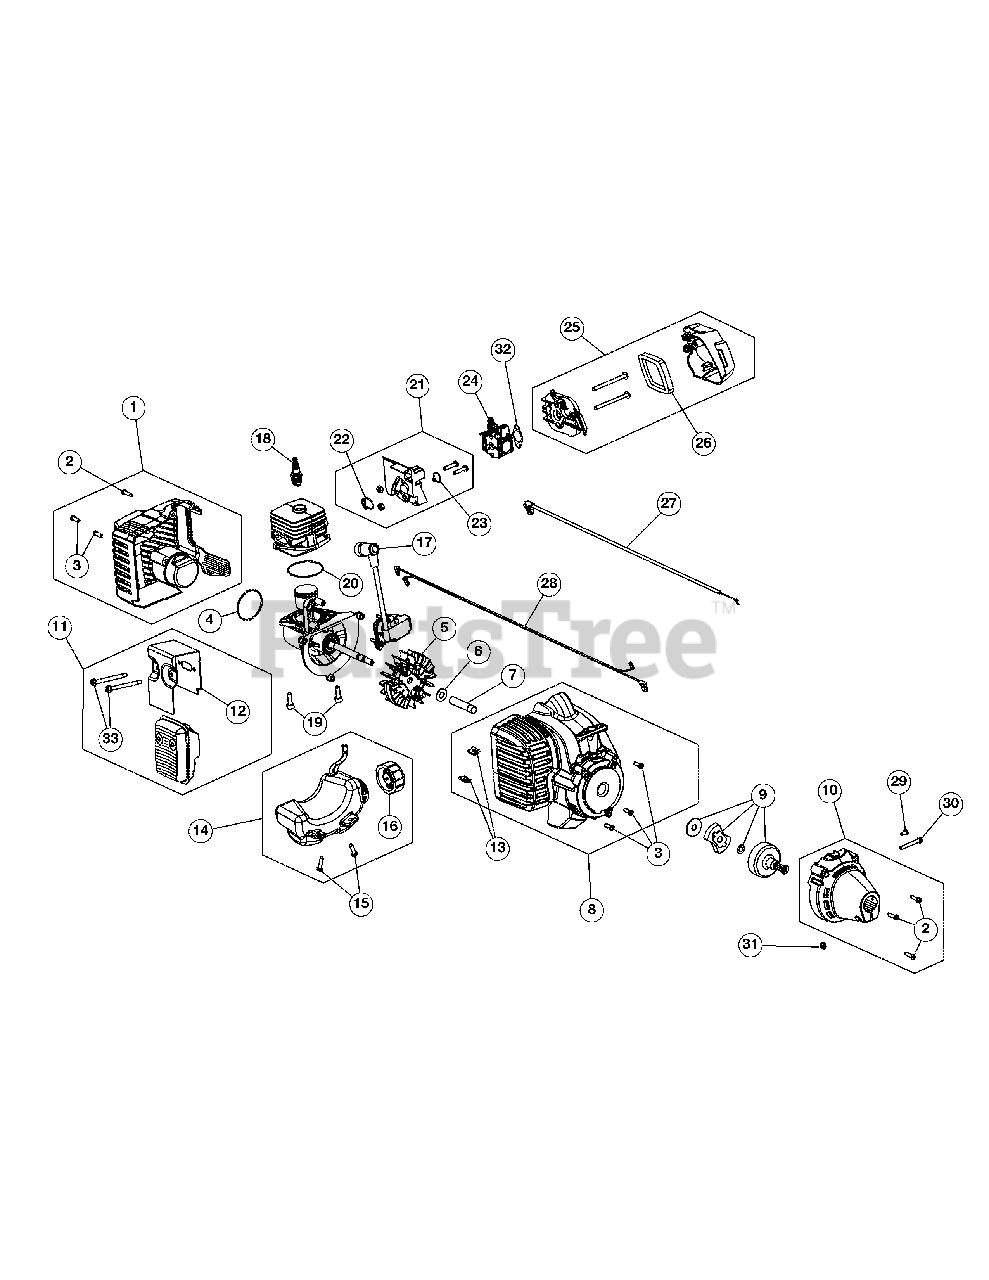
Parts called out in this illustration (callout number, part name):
1	Rear Cover Assembly (Incl. 2 & 3)
2	Cover Screw
3	Housing Screw
4	O-Ring
5	Flywheel Assembly
6	Washer
7	Spacer
8	Starter Housing (Incl. 3 & 13)
9	Starter Clutch Assembly
10	Clutch Cover (Incl. 2)
11	Muffler Assembly (Incl. 12 & 33)
12	Muffler Gasket
13	U-shaped Nut
14	Fuel Tank Assembly (Incl. 15 & 16)
15	Tank Screw
16	Fuel Cap
17	Module Assembly
18	Spark Plug
19	Crankcase Bolt
20	Crankcase O-Ring
21	Insulator Assembly (Incl. 22 & 23)
22	Insulator O-Ring
23	Carburetor O-Ring
24	Carburetor
25	Aircleaner Cover Assembly (Incl. 26)
26	Aircleaner Filter
27	Throttle Cable
28	Lead Wires
29	Anti-rotation Screw
30	Clamp Screw
31	Clamp Nut
32	Air Cleaner Gasket
33	Muffler Screws
